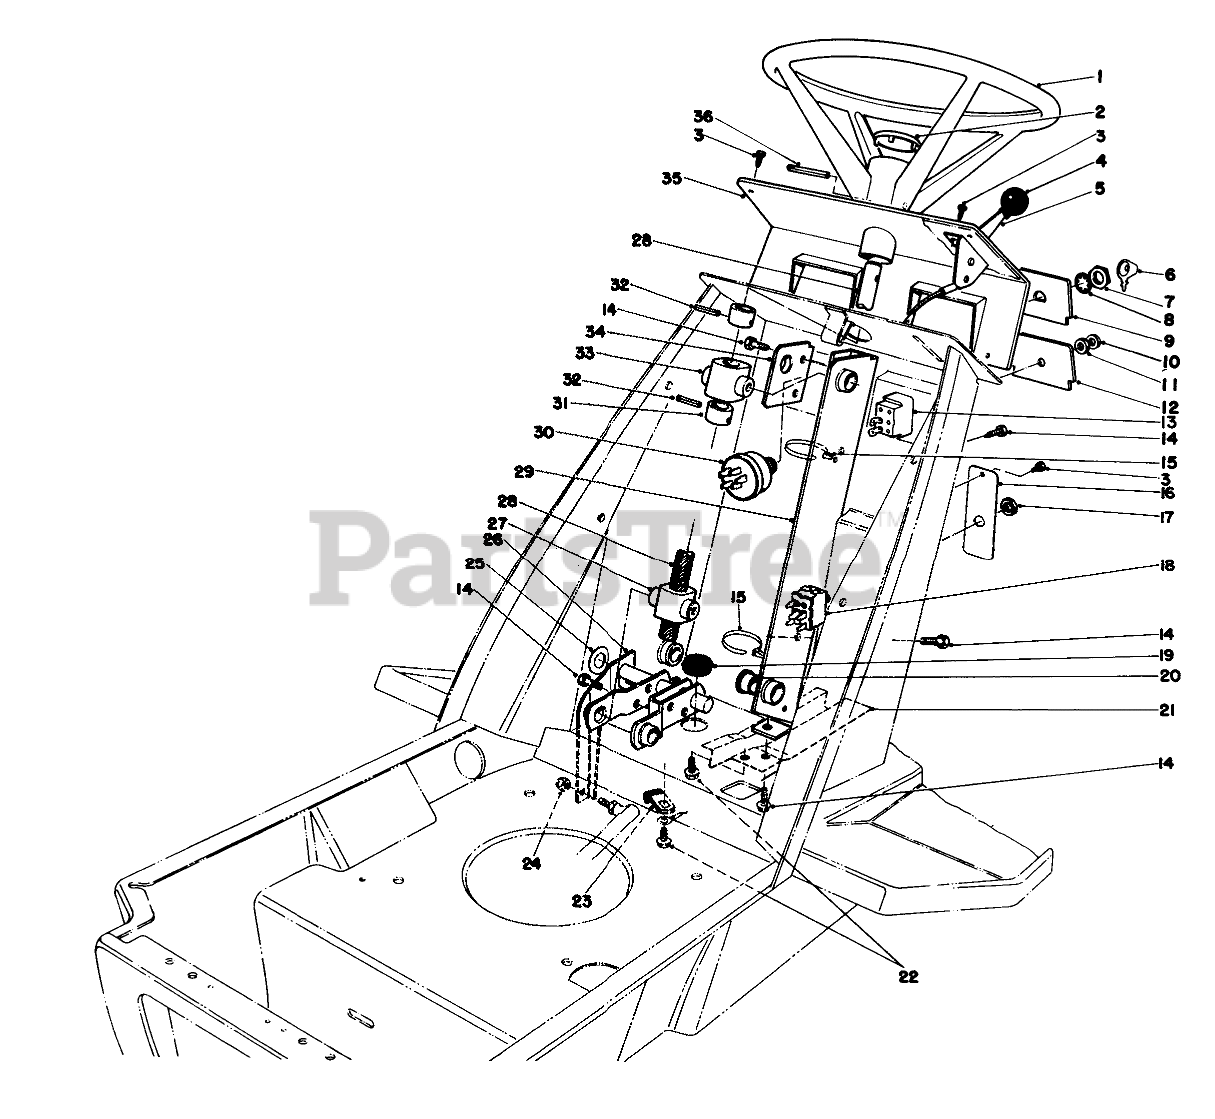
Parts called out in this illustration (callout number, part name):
1	Steering Wheel Assembly (Incl. Ref. #2)
2	Cap-Steering Wheel
3	SCREW-HWHTF
4	KNOB-CONTROL
5	Throttle Control (Incl. Ref. #4)
6	Key
7	NUT-HH
8	WASHER-TOOTH, INTERNAL
9	DASH PANEL INSERT
10	NUT-BULB
11	NUT-LOCK
12	DASH PANEL INSERT
13	Light Switch (Incl. Ref. #10 & 11)
14	SCREW-HWHTF
15	Cable Tie (Incl. w/Wire Harness)
16	CLUTCH PLT SWITCH
17	NUT
18	Switch-Clutch (Incl. Ref. #17)
19	Grommet (Incl. w/Wire Harness)
20	BEARING-FLANGE
21	WIRE HARNESS SHLD B
22	SCREW
23	CLIP-FUEL LINE
24	NUT-HEX
25	WASHER
26	STEERING LINK WA BO
27	FOLLOWER STEER SHAFT
28	STEERING SHAFT
29	STRG BRKT B
30	Ignition Switch (Incl. Ref. #6-8)
31	STRG SHAFT COLLAR
32	PIN-SPRING
33	BRG STEERING SHAFT
34	STRG BRG SUPPORT
35	DASH PANEL
36	PIN-ROLL
